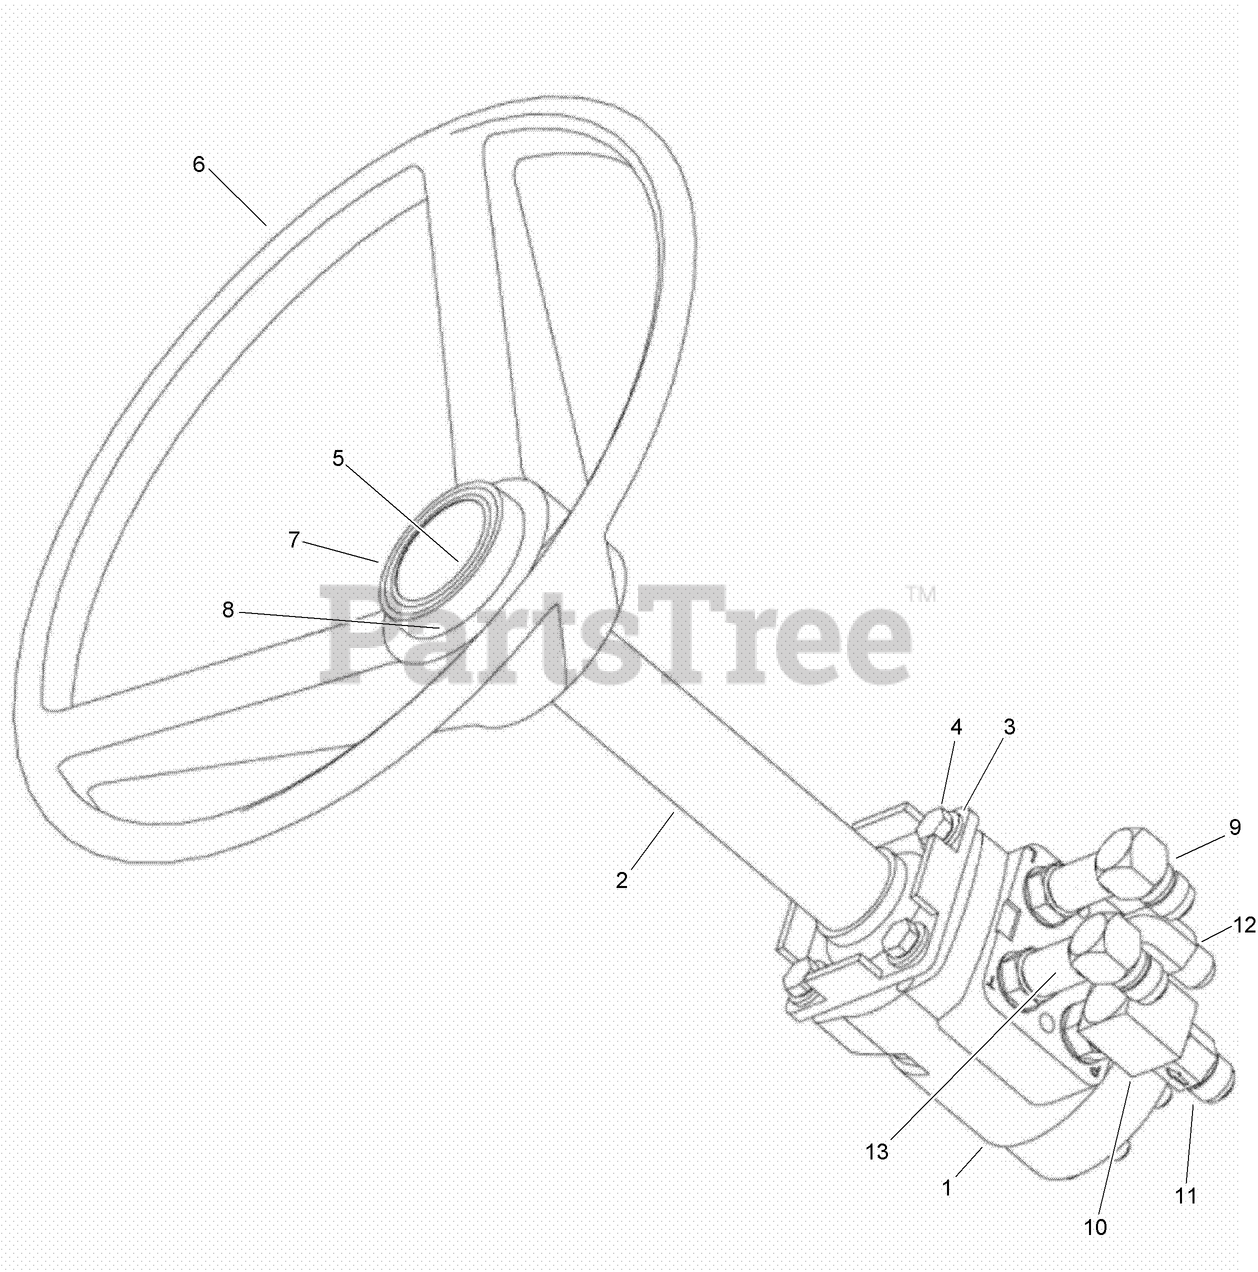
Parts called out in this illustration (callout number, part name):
1	HYD STEERING CONTROL VALVE ASM
2	STEERING COLUMN ASM
3	WASHER-FLAT
4	BOLT-hex, 3/8 NC x 1-1/2 inch
6	WHEEL-STEERING
7	CAP-STEERING WHEEL
11	VALVE-CHECK
12	ELBOW-90 Adj 37FL, 1/2 Tube
13	ELBOW-90 Adj 37FL 1/4 Tube
